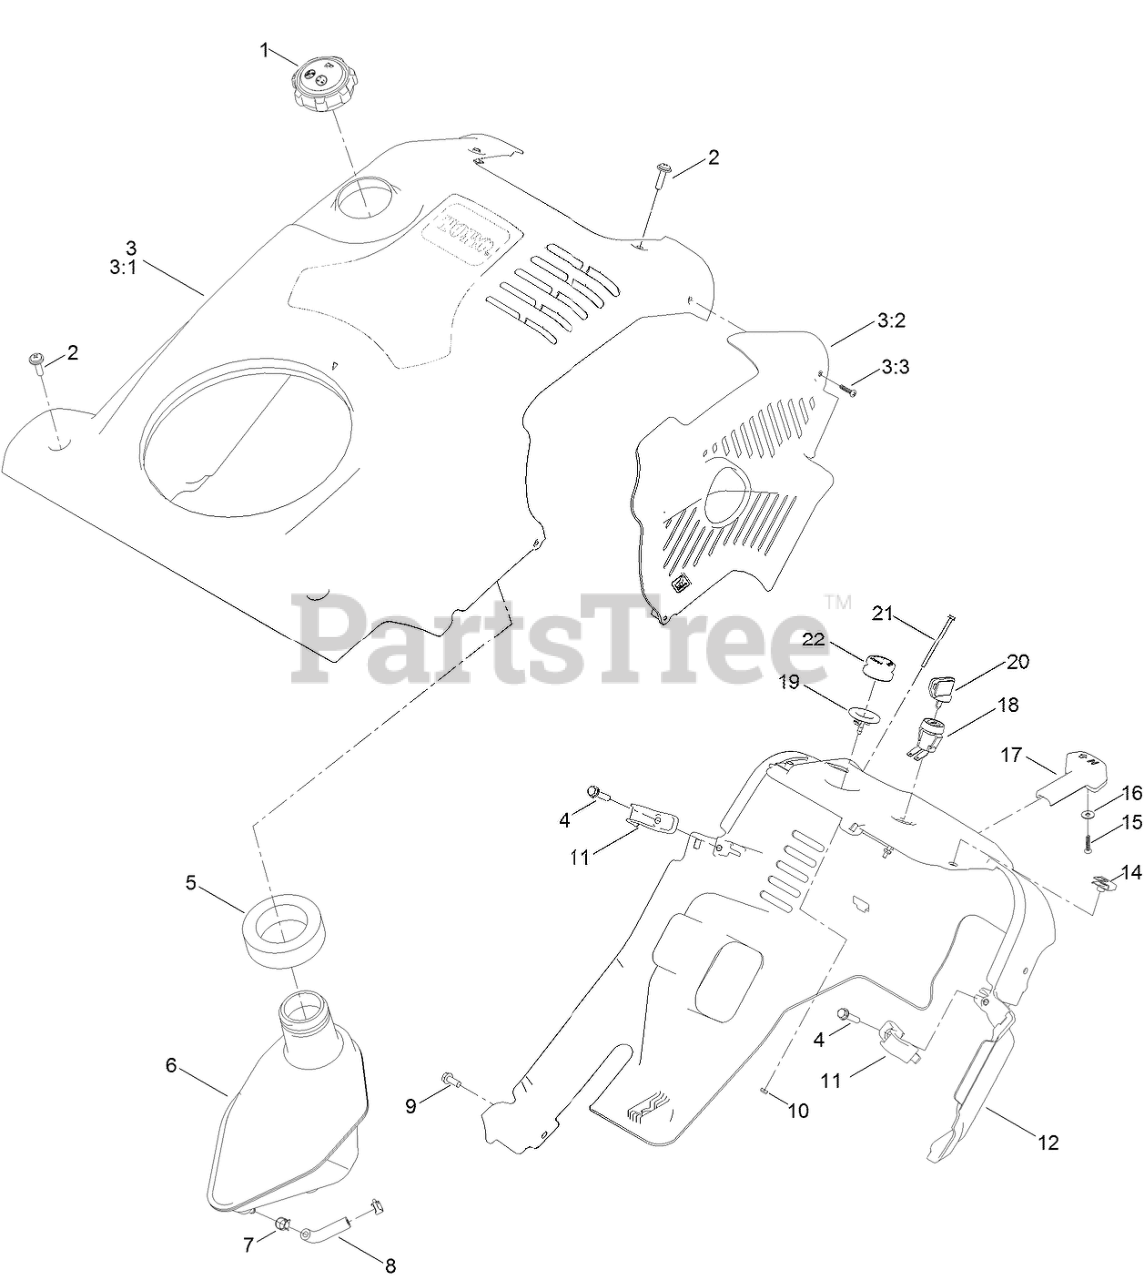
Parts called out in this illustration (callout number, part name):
1	CAP-GAS
2	SCREW-PPH
3	SHROUD ASM
3:2	BAFFLE-EXHAUST
3:3	SCREW-PPH
4	SCREW-PLASTITE
5	SEAL-TANK
6	TANK-FUEL, GAS
7	CLAMP-HOSE
8	HOSE-FUEL
9	SCREW-HWH
10	NUT-HEX
11	CLIP-SHROUD
12	SHROUD-LOWER
15	SCREW-PPH
16	WASHER-PLAIN
17	KNOB-CHOKE
18	SWITCH
19	BODY-PRIMER
20	KEY-IGNITION
21	SCREW-HWH
22	BULB-PRIMER
